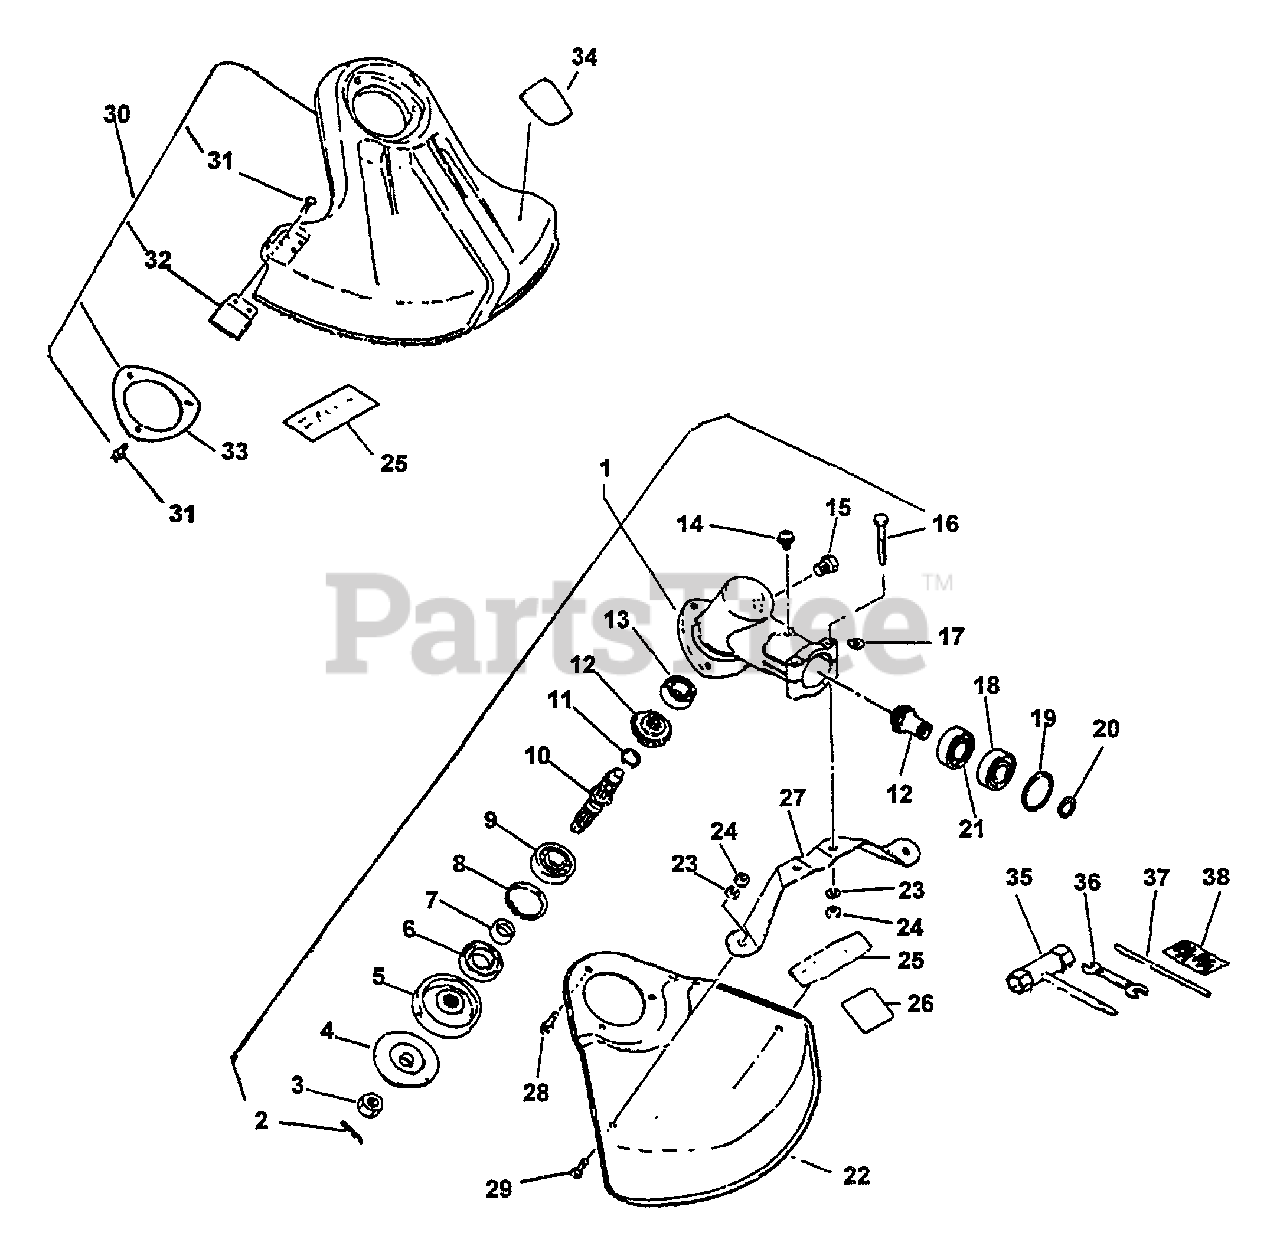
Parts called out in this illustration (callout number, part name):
1	GEAR CASE ASSY
2	PIN, SPLIT - 2X22
3	NUT - 10 -- LEFT HAND
4	ADAPTOR, BLADE - LOWER
5	ADAPTOR, BLADE - UPPER
6	SEAL, OIL
8	RING, RETAINING - 32
9	BEARING, BALL - 6201
10	GEAR - SHAFT
11	RING, RETAINING - 10
12	GEAR SET - BEVEL
13	BEARING, BALL - 609
14	SCREW - 5X10
15	BOLT - 5X8
16	BOLT - 5X35
18	BEARING, BALL - 6900Z
19	RING, RETAINING - 22
20	RING, RETAINING - 12
21	BEARING, BALL - 6900
22	DEBRIS SHIELD KIT - METAL
23	LOCKWASHER - 5
25	LABEL - ECHO
26	LABEL - CAUTION
27	BRACKET, SHIELD
28	SCREW - 5X10
29	SCREW - 5X8
30	DEBRIS SHIELD KIT
31	SCREW - 5X16
32	KNIFE, TRIMMER LINE
33	PLATE, SHIELD
34	LABEL - CAUTION
35	T-WRENCH - 17X19mm
36	SPANNER - 8X10mm
37	LOCKING TOOL
38	PIN, SPLIT - 2X22
